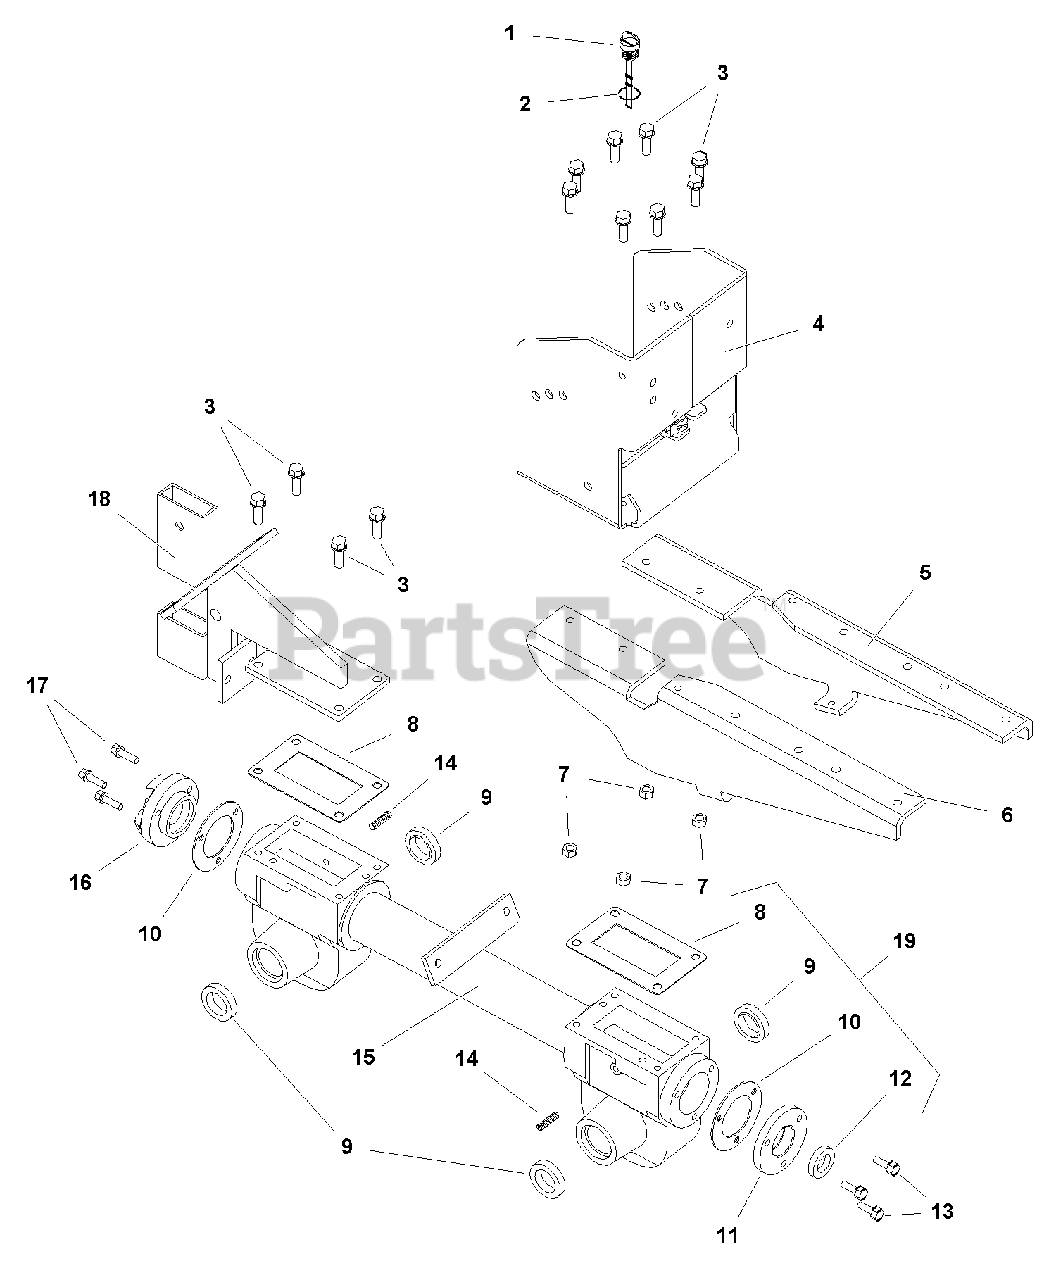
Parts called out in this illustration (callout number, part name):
2	O-RING, Dipstick
3	BOLT, Hex Flange Head 5/16"-18 x 3/4"
4	COVER PLATE & MOUNT
5	BRACKET, Engine Mount LH
6	BRACKET, Engine Mount RH
7	NUT, Hex Flange 5/16"-18 Two, Way Lock GA
8	GASKET, Housing & Transmission Cover
9	SEAL, Housing
10	GASKET, Bearing Cap Front, Rear
11	CAP, Rear Bearing
12	SEAL, Oil, Drive Shaft
13	BOLT, Hex Flange Head 1/4"-20 x 3/4"
14	PLUG, Pipe Socket Head 1/4"-18 Oil Check
15	TRANSMISSION, Tiller Casting
16	CAP, Rear Bearing
17	BOLT, Hex Flange Head 1/4"-20 x 7/8"
18	BRACKET, Depth Regulator
19	GASKET KIT, Oil Seal (Includes Ref. 8, 9, 10, and 12)
